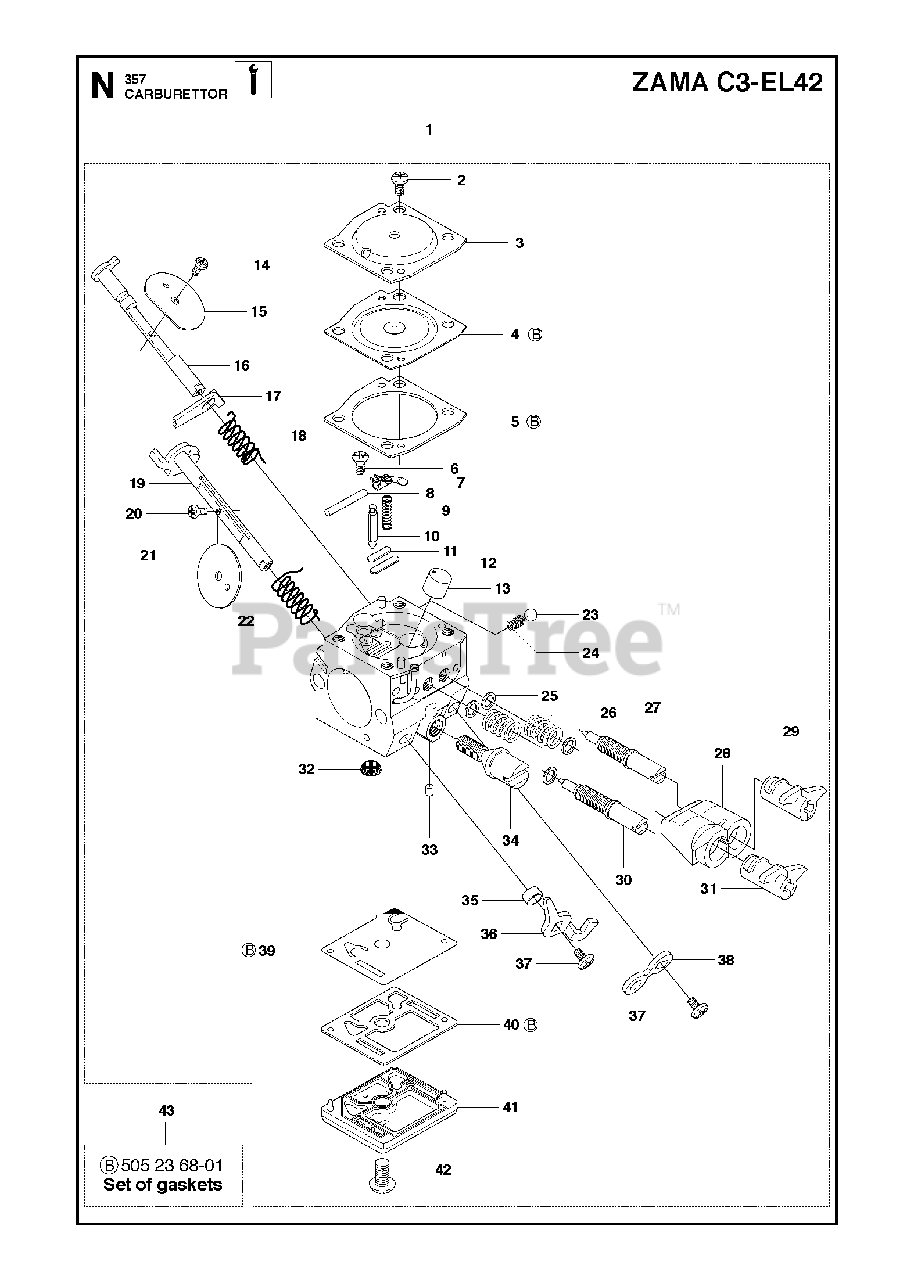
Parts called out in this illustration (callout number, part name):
1	RP CARBURETOR
2	SCREW
3	COVER
4	DIAPHRAGM
5	GASKET
6	SCREW
7	LEVER
8	PIN FULCRUM
9	SPRING
10	VALVE
11	PLUG
12	PLUG
13	NOZZLE ASSY
14	SCREW
15	CHOKE FLAP
16	CHOKE SHAFT
17	THROTTLE LOCK
18	SPRING
19	Throttle Shaft
20	SCREW
21	THROTTLE FLAP
22	SPRING
23	BALL
24	SPRING
25	WASHER
26	SPRING
27	JET
28	SLEEVE
29	LIMITER CAP
30	LOW SPEED NEEDLE
31	LIMITER CAP
32	STRAINER
33	PLUG
34	SCREW
35	BUSHING
36	LEVER
37	SCREW
38	LEVER
39	PUMP DIAPHRAGM
40	GASKET
41	COVER
42	SCREW
43	KIT GASKET
